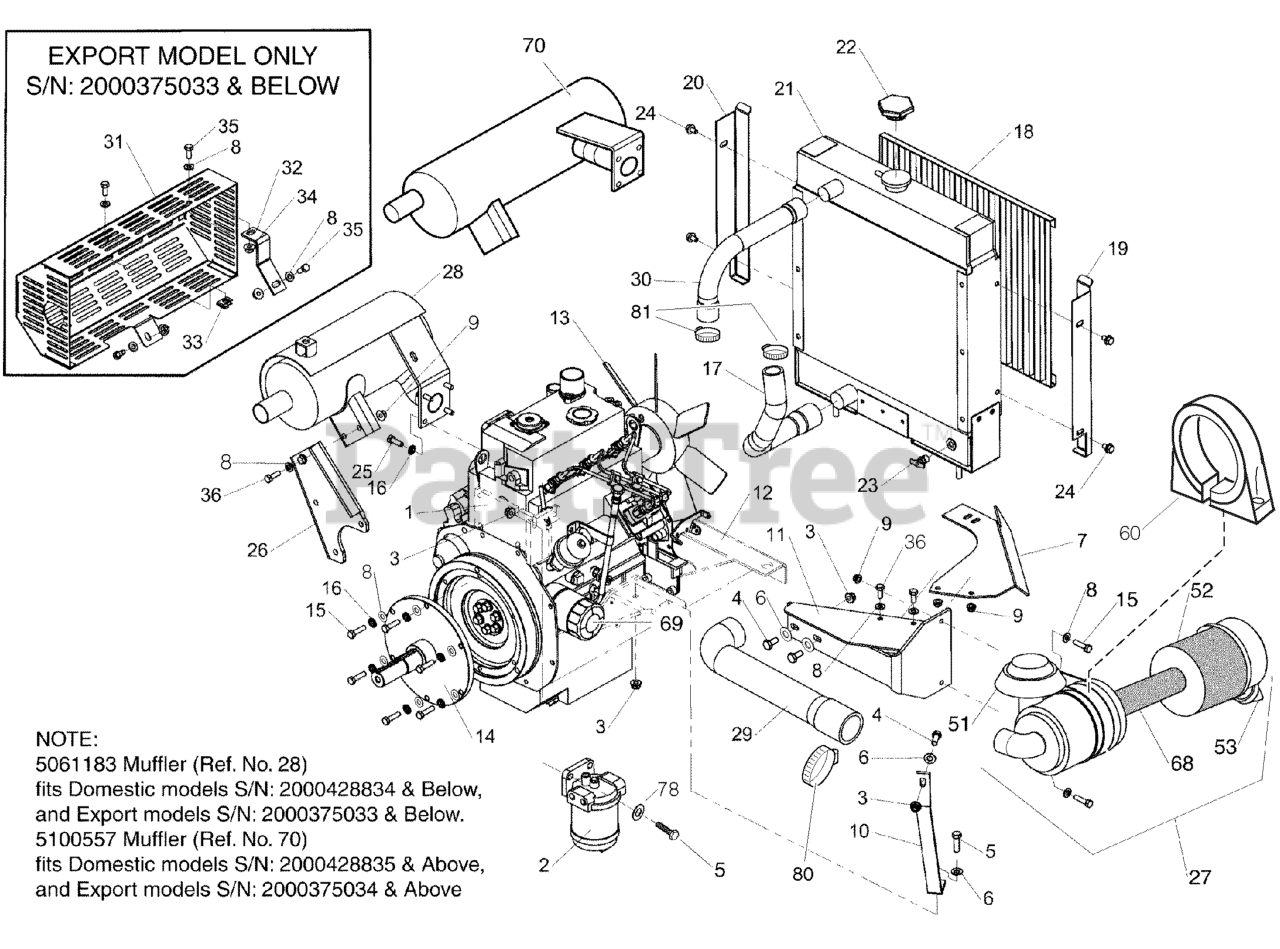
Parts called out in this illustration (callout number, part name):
1	FUEL FILTER MOUNT
2	FUEL FILTER ASSEMBLY (19B & 19C)
2	FUEL FILTER ELEMENT ONLY
3	NUT, 3/8-16 HEX NYLOCK FLANGE
4	BOLT, 3/8-16 X 1-1/4" GD5 CZ
5	BOLT, 3/8-16 X 1-1/2" GD5 CZ
6	WASHER, 3/8" GD.9 FLAT
7	BAR, AIR FILTER MOUNT
8	WASHER, 5/16" SAE
9	NUT, 5/16-18 HEX NYLOCK FLANGE
10	SUPPORT, AIR FILTER
11	WELD, AIR FILTER MOUNT
12	ENGINE & RADIATOR MOUNT
13	ENGINE, 28HP Caterpillar
14	SHAFT, 3011C PTO
15	BOLT, 5/16-18 X 1-1/4" GD5 YZ
16	WASHER, 5/16 LOCK CZ
17	HOSE, LOWER RADIATOR
18	RADIATOR SCREEN
19	BRACKET, SCREEN MOUNT, RH
20	BRACKET, SCREEN MOUNT, LH
21	RADIATOR
22	CAP, RADIATOR - NET
23	PETCOCK VALVE
24	BOLT, 5/16-18 X 1/2" FLANGE SPECIAL
25	BOLT, M8-1.25 X 25MM GR 8.8
26	MOUNT, MUFFLER
27	AIR CLEANER ASSY
28	MUFFLER
29	AIR FILTER HOSE
30	UPPER RADIATOR HOSE
31	MUFFLER GUARD
32	MUFFLER GUARD BRACKET
33	BODY CLIP, 5/16-18-7GA MATERIAL
34	NUT, 5/16-18 HEX SERRATED FLANGE (LARGE)
35	BOLT, 5/16-18 X 3/4 GD5
36	BOLT, 5/16-18 X 1" GD5 YZ
37	OIL FILL CAP
38	FUEL SOLENOID
39	WATER PUMP
40	WATER PUMP GASKET
41	THERMOSTAT
42	THERMOSTAT GASKET
43	DIPSTICK
44	OIL PAN PLUG
45	STARTER MOTOR
46	ALTERNATOR
47	BELT
48	FUEL PUMP
49	FUEL PUMP GASKET
50	GLOW PLUG
51	CAP, A/C RAIN
52	ELEMENT ASSY
53	AIR CLEANER DUST VALVE
54	EXHAUST MANIFOLD GASKET
55	OIL PRESSURE SWITCH
56	WATER TEMPERATURE SWITCH
57	SEAL, OIL FILL
58	REAR MAIN SEAL
59	FRONT MAIN SEAL
60	BRACKET, AIR CLEANER ASSY
61	INJECTOR ASSEMBLY
62	WASHER, FUEL SOLENOID
63	WASHER, OIL DRAIN PLUG
64	PARTS MANUAL, ENGINE
65	VALVE COVER GASKETS
66	EXPANSION TANK, Complete
67	CAP
68	AIR FILTER ELEMENT (SECONDARY)
69	ENGINE OIL FILTER
70	MUFFLER, 3011C CAT ENGINE - CE
78	WASHER, 3/8 SAE
80	CLAMP, HOSE, 2-3/4"
81	CLAMP, HOSE, 1-3/4"
82	SENDER, WATER TEMPERATURE
